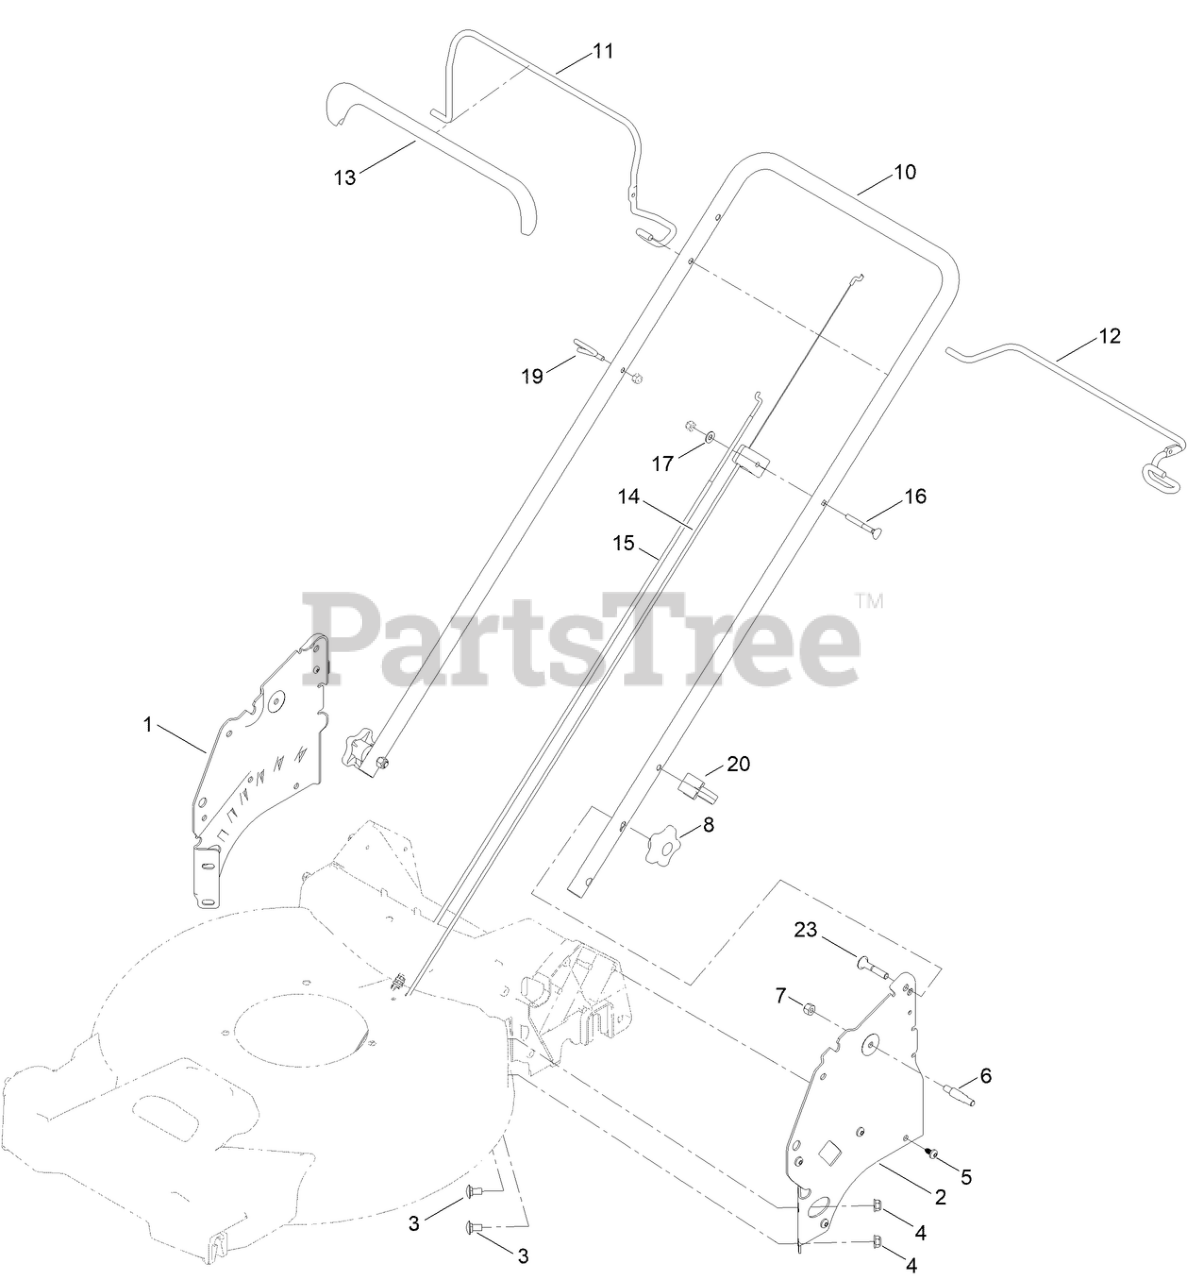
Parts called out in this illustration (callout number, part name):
1	PLATE-HOC, RH
2	PLATE-HOC, LH [BLK-TXT]
3	SCREW-CARR
4	NUT-FLANGE, NI
5	SCREW-PLASTIC,PH
6	BOLT-SHOULDER, HANDLE
7	NUT-LOCK, NI
8	KNOB-HANDLE
10	HANDLE-UPPER
11	BAIL-BRAKE
12	BAIL-TRACTION
13	COVER-BAIL
14	CABLE-BRAKE
15	CABLE-TRACTION
16	SCREW-HANDLE
17	WASHER-FLAT
19	GUIDE-ROPE
20	GUIDE-CABLE
23	SCREW-CARR
